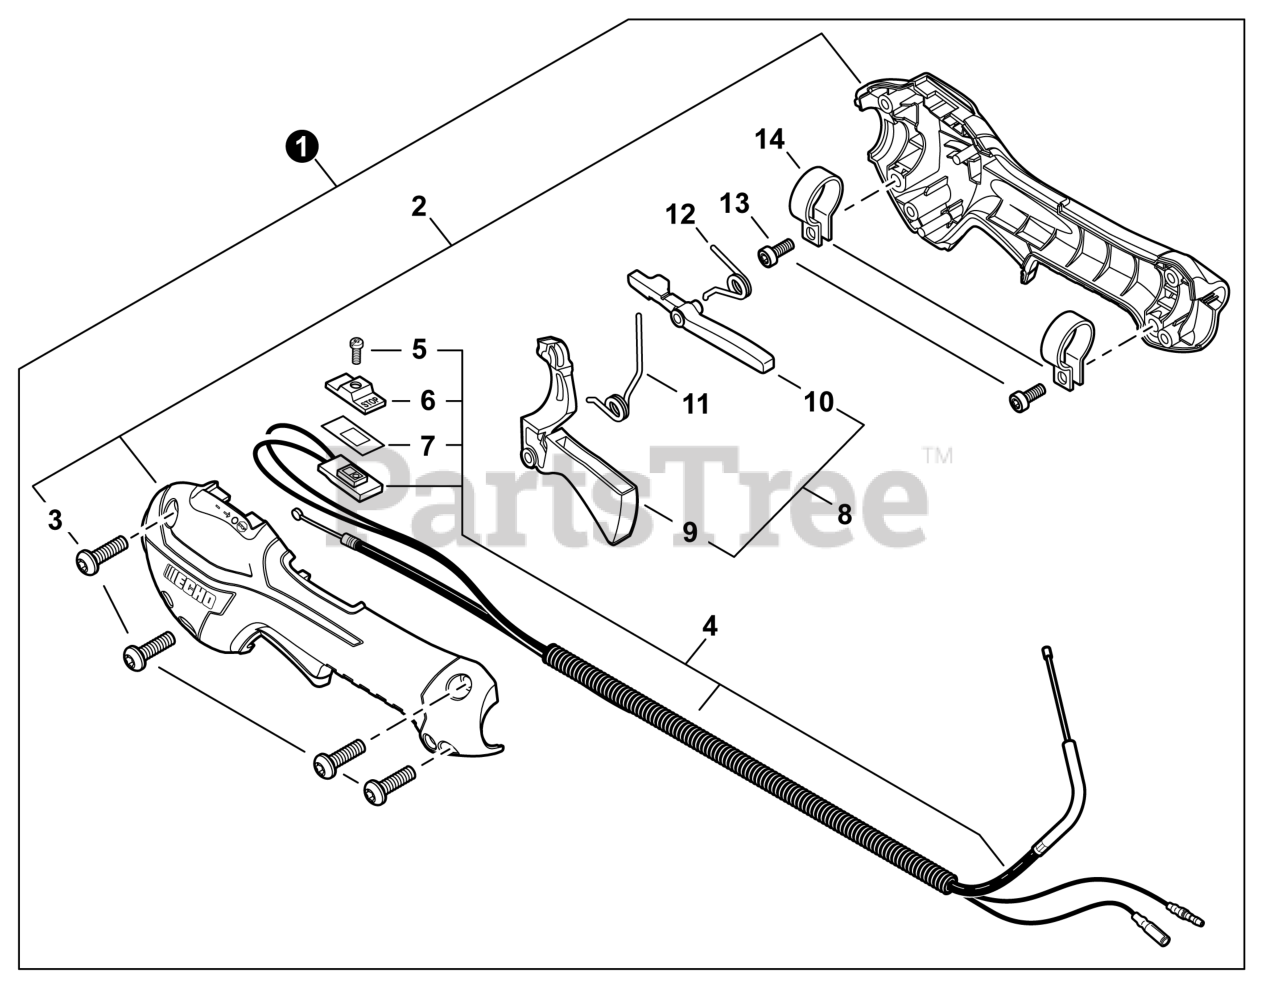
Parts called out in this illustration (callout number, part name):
1	CONTROL HANDLE ASSY
2	CONTROL HANDLE KIT
3	BOLT, TORX 5x16
4	CABLE ASSY, CONTROL
5	SCREW 3x10
6	KNOB, SWITCH - ORANGE
7	SEAL, SWITCH
8	THROTTLE LOCKOUT KIT
9	TRIGGER, THROTTLE
10	LEVER, THROTTLE LOCKOUT
11	SPRING, TORSION
12	SPRING, TORSION
13	BOLT, TORX 5x16
